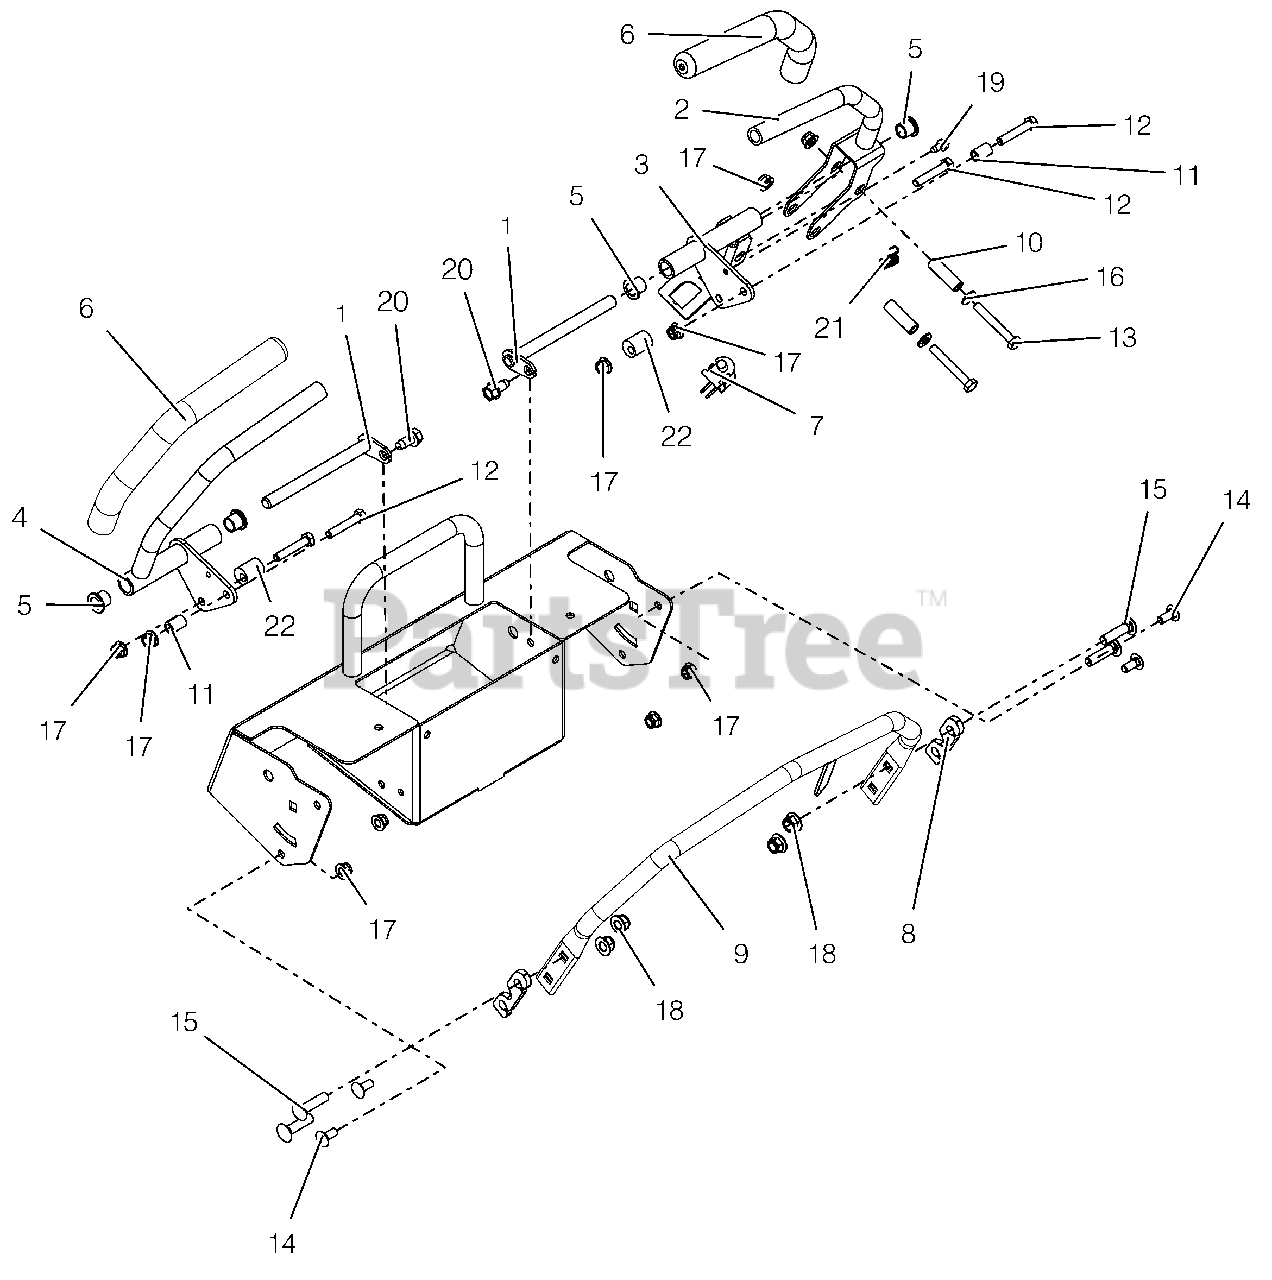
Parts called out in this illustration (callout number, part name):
1	WLDT, PIN AND LOCK Y
2	WMT, CONTROL ARM OPC
3	WMT, CONTROL ARM (LH)
4	WMT, CONTROL ARM (RH)
5	BRG, FLG .500X.620X.500 BRNZ
6	GRIP, HANDLEBAR
7	SWITCH- SNAP MTG N.O.
8	SHIM, 5 DEG SPEED BAR
9	BAR, FORWARD STOP PRO-STANCE
10	BSHG-SLV .325X.49X1.56
11	BSHG-SLV .328X.50X.75
12	@BLT-HEX .31-18X1.75 GR5 YWZC
13	@BLT-HEX .31-18X2.25 GR5 YWZC
14	@BLT-RDHDSQNK .31-18X.75 G5YZ
15	@BLT-RDHDSQNK .38-16X1.50 G5YZ
16	@WSHR-FL-STL.344X.688X.065YWZC
17	@NUT-LK-NYL-FLG .31-18 YWZC
18	@NUT-LK-NYL-FLG .38-16 YWZC
19	SCR-TAP .25-20X.50 HWH TR YWZ
20	@SCR-TAP .38-16X.75 HWH TR YWZ
21	SPRING, EXT. .043X.438X1.64
22	ECCENTRIC
